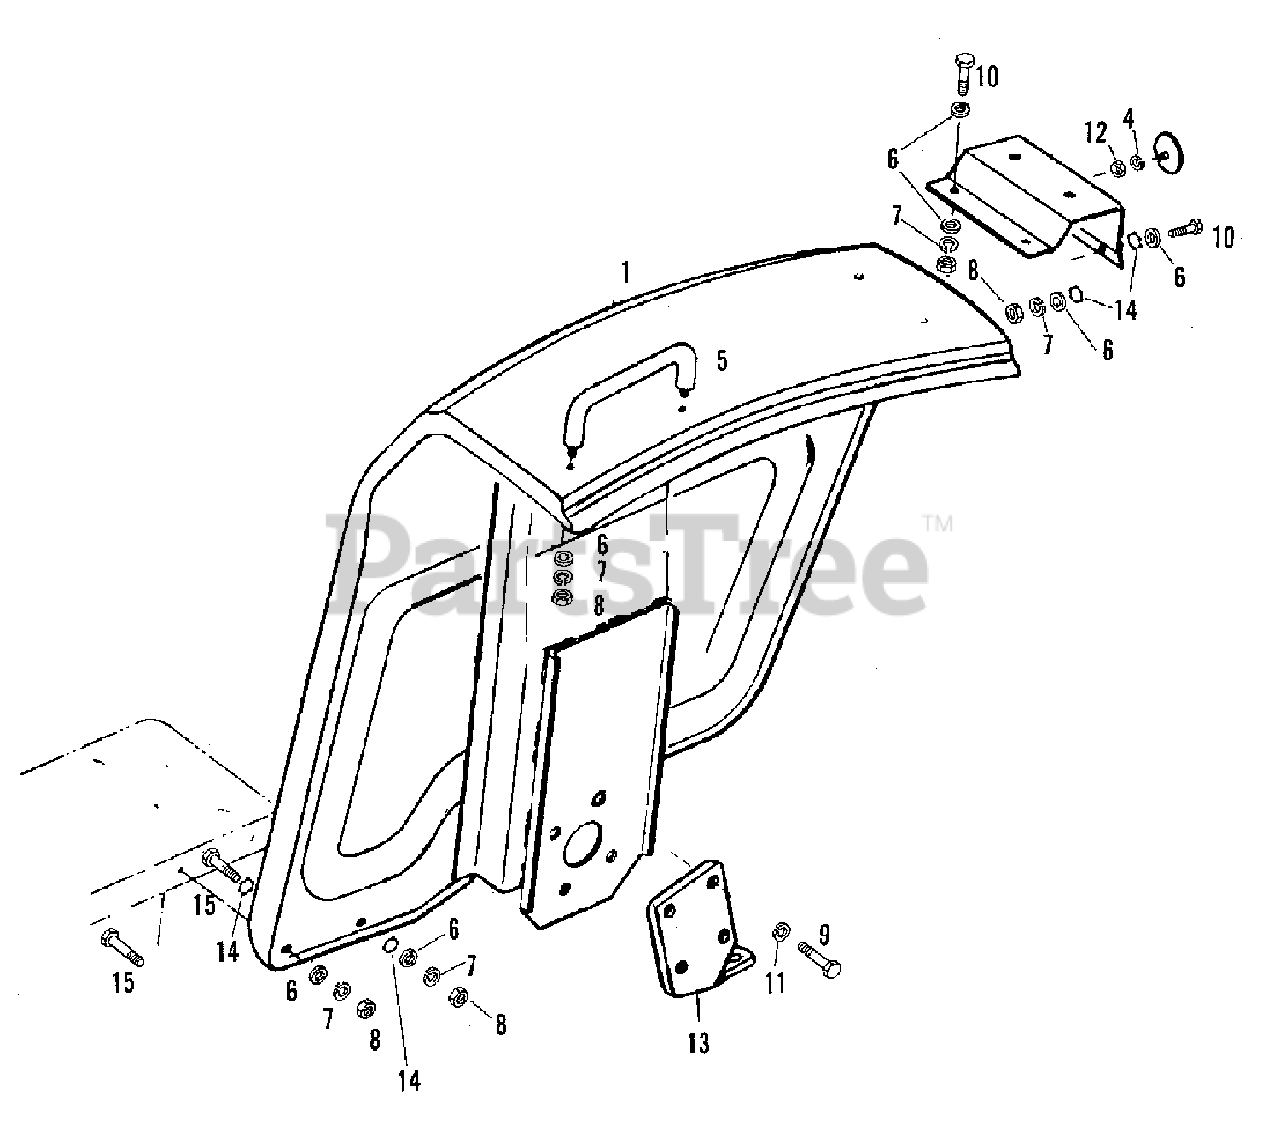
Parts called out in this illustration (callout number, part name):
1	FENDER, L.H.
1	FENDER, R.H.
2	BRACKET, warning lamp
3	REFLECTOR
4	LOCKWASHER
6	WASHER
7	LOCKWASHER
11	LOCKWASHER
13	BRACKET, L.H., chain
13	BRACKET, R.H., chain
